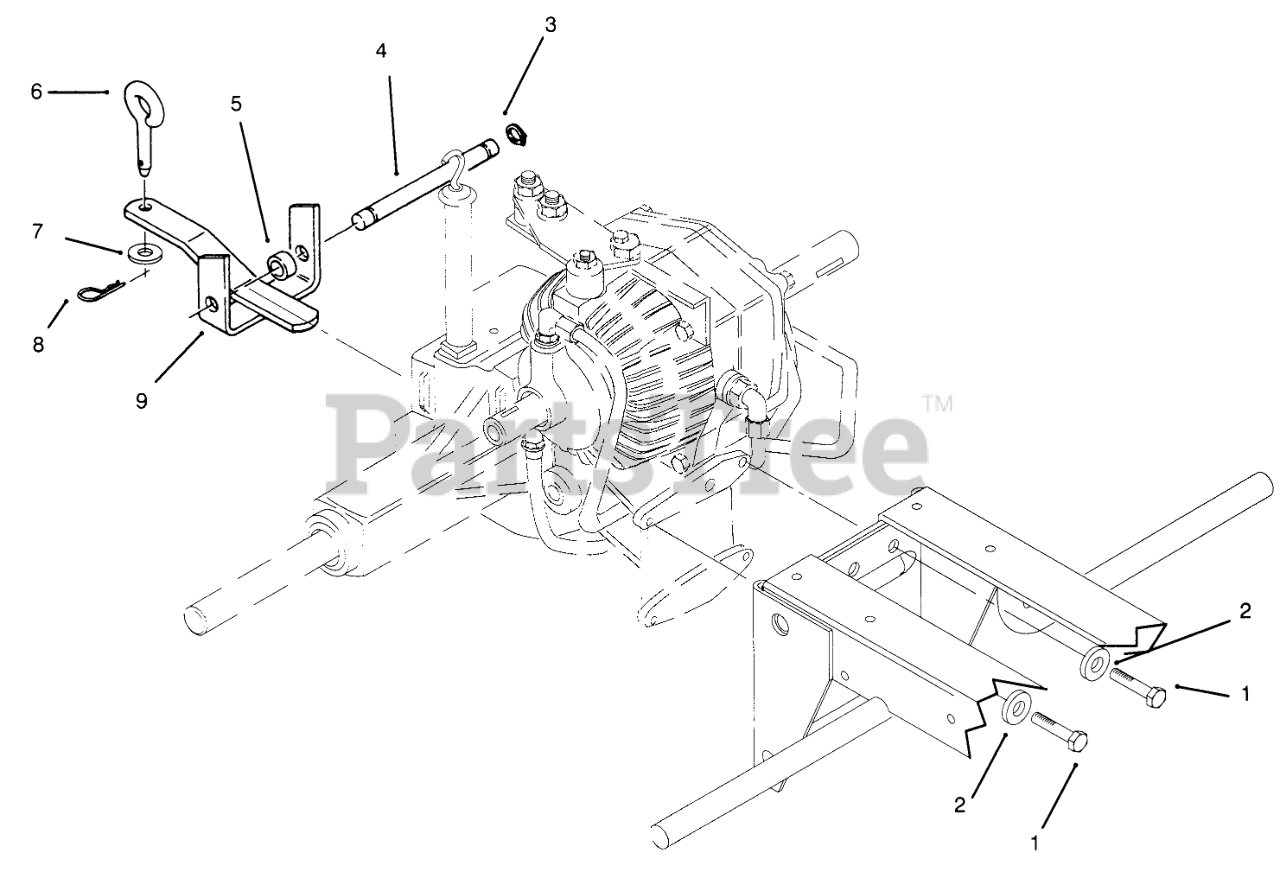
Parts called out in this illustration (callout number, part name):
1	SCREW-HH
2	WASHER-LOCK
3	E-RING
4	PIN-STATIONARY HITCH
5	Spacer
6	PIN-TOOL
7	WASHER-FLAT
8	Hairpin Cotter
9	Hitch
